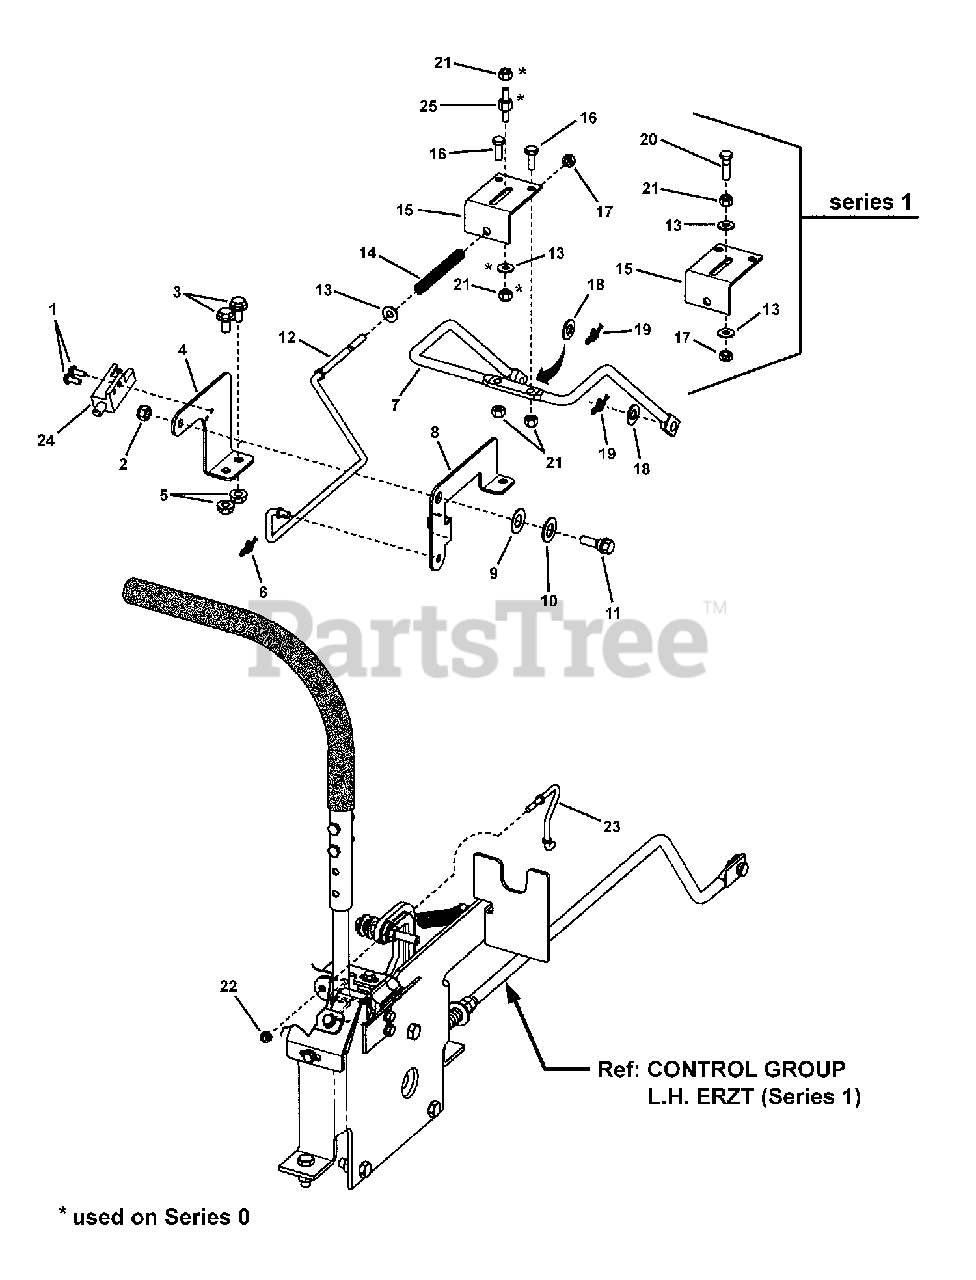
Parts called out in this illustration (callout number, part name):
1	SCREW, #10-24 x 1/2" Hex Washer Self-Tap (Torx)
2	NUT, 5/16-18 Hex Nyloc
3	BOLT, 5/16-18 x 5/8" Hex Flange Lock, GR 5
4	BRACKET, Park Brake, LH Lower
5	NUT, 5/16-18 Hex Flange Lock, GR 5
6	COTTER PIN, 3/8" Self-Locking
7	ROD, Park Brake
8	BRACKET, Park Brake, RH Lower
9	WASHER, 1/2 x .090 Flat
10	WASHER, .531 x 1.0 x .063 Flat
11	SHOULDER BOLT, 5/16-18 x 1"
12	ROD, Park Brake (1/4-20 thread)
13	WASHER, .28 x .63 x .06 Flat, GR 5
14	SPRING, Compression
15	BRACKET, Park Brake
16	SCREW, 1/4-20 x 3/4" Hex Head Cap, GR 5
17	NUT, 1/4-20 Hex Top Lock, GR B
18	WASHER, 3/8" Flat SAE
19	COTTER PIN, 1/2 Self Locking, YZ
20	SCREW, 1/4-20 x 1" Hex Head Cap, GR 5
21	NUT, 1/4-20 Hex Nyloc YZ
22	NUT, 10-24 Hex Nyloc
23	HOOK, Park Brake
24	SWITCH- DPDT
25	ROD, Hanger (1/4-20 both ends)
